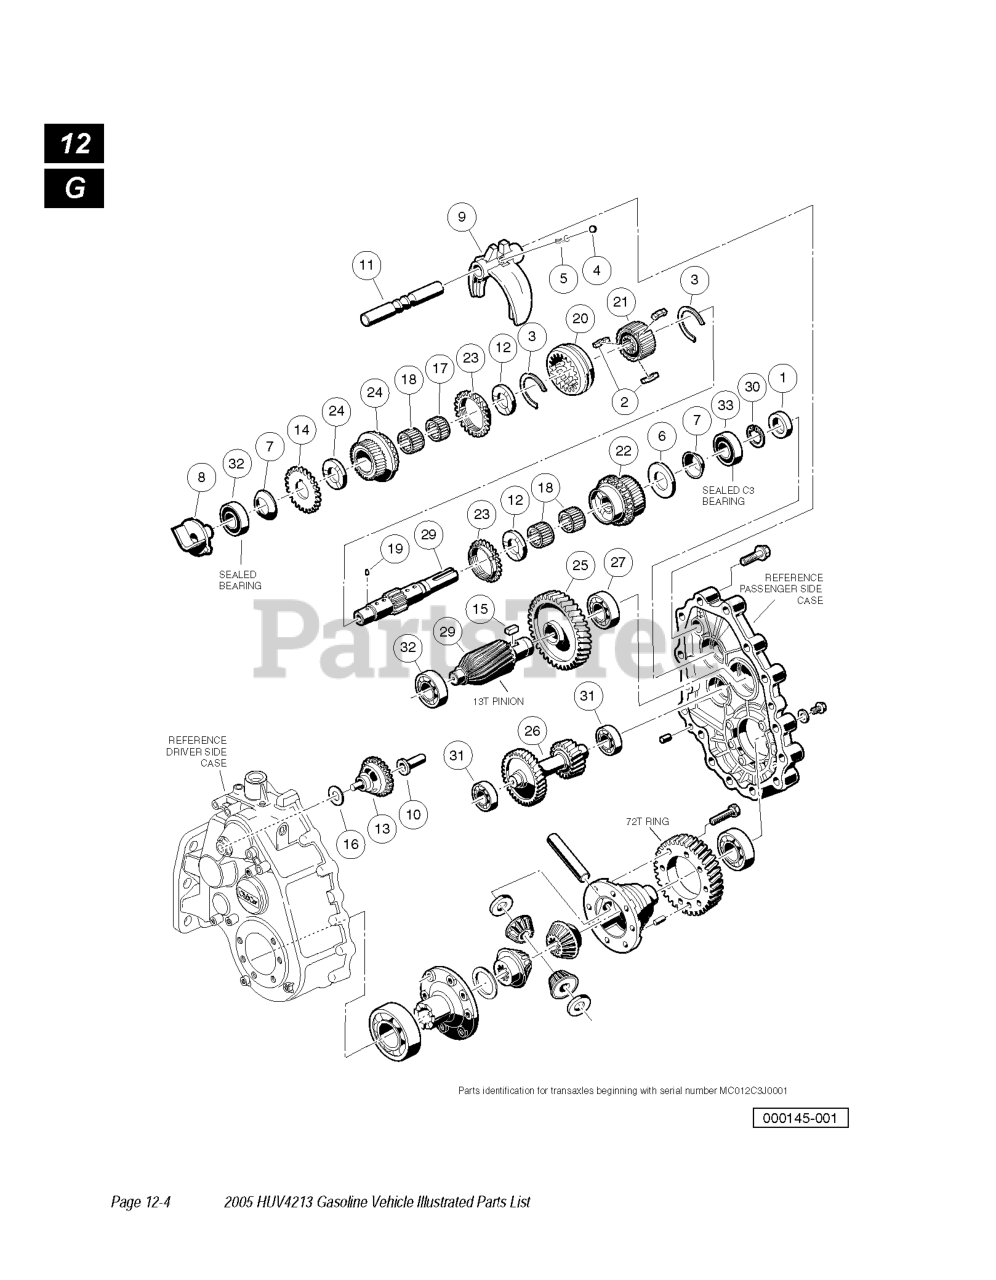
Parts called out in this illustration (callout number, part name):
2	SYNCHRO INSERT
3	SYNCHRO SPRING
4	Shifter Ball
5	SHIFTER SPRING
6	THRUST WASHER
7	SPRING WASHER
9	FORK-SHIFT
10	SLEEVE - GOVERNOR
12	PLATE-THRUST
13	GOVERNOR ASSEMBLY
17	BEARING, NEEDLE
18	NEEDLE BEARING
19	PIN, .116" DIA X .264 DOWEL
20	SLEEVE, SYNCHRO
21	HUB, SYNCHRO CLUTCH
22	GEAR ASSY, 16 DEG FRT SYNCHRO
23	RING, 16 DEGREE SYNCHRONIZER
24	GEAR ASSEMBLY INPUT 25 TOOTH
25	GEAR 70 TOOTH
26	GEAR CLUSTER IDLER
27	BEARING - BALL TMB206C
28	GEAR, HELICAL, 13T
29	SHAFT, TRANS, W/ CIRCLIP
30	CIRCLIP, TRANS INPUT SHAFT
32	SEALED BALL BEARING (7336)
33	SEALED BALL BEARING(101927801)
